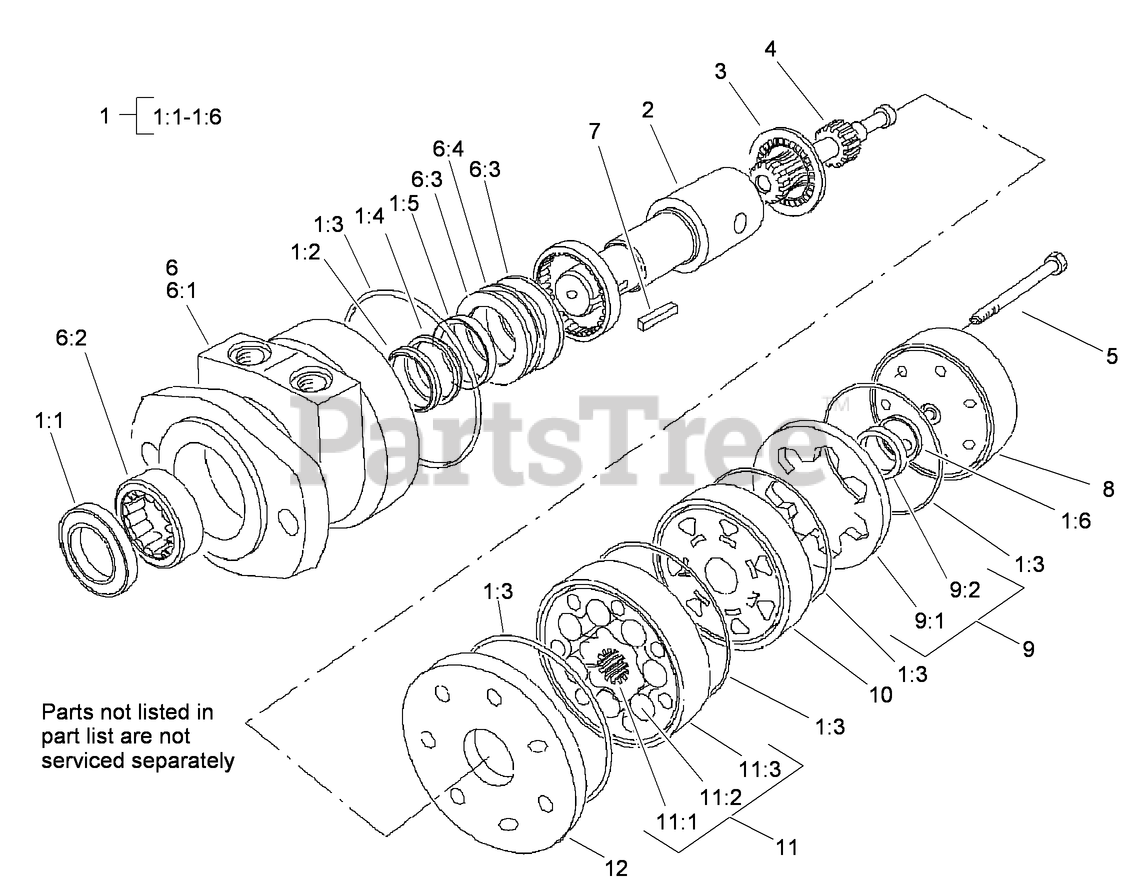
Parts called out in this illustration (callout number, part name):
1	SEAL KIT
1:1	Seal-Dirt and Water
1:2	BACKUP-RING
1:3	Seal-Shaft
1:4	Washer-Backup
1:5	SEAL-SQUARE, RING (INNER)
1:6	Seal-Commutator
2	COUPLING SHAFT
3	BEARING-THRUST
4	LINK-DRIVE
5	SCREW-HH
6	HOUSING ASM
6:1	HOUSING
6:2	Bearing
6:3	Washer-Thrust
6:4	Bearing-Thrust
7	KEY-SQUARE
8	END COVER ASM
9	COMMUTATOR ASM
9:1	Ring-Commutator
9:2	Commutator
10	MANIFOLD
11	ROTOR SET
11:1	Rotor
11:2	Vane
11:3	Stator
12	PLATE-WEAR
